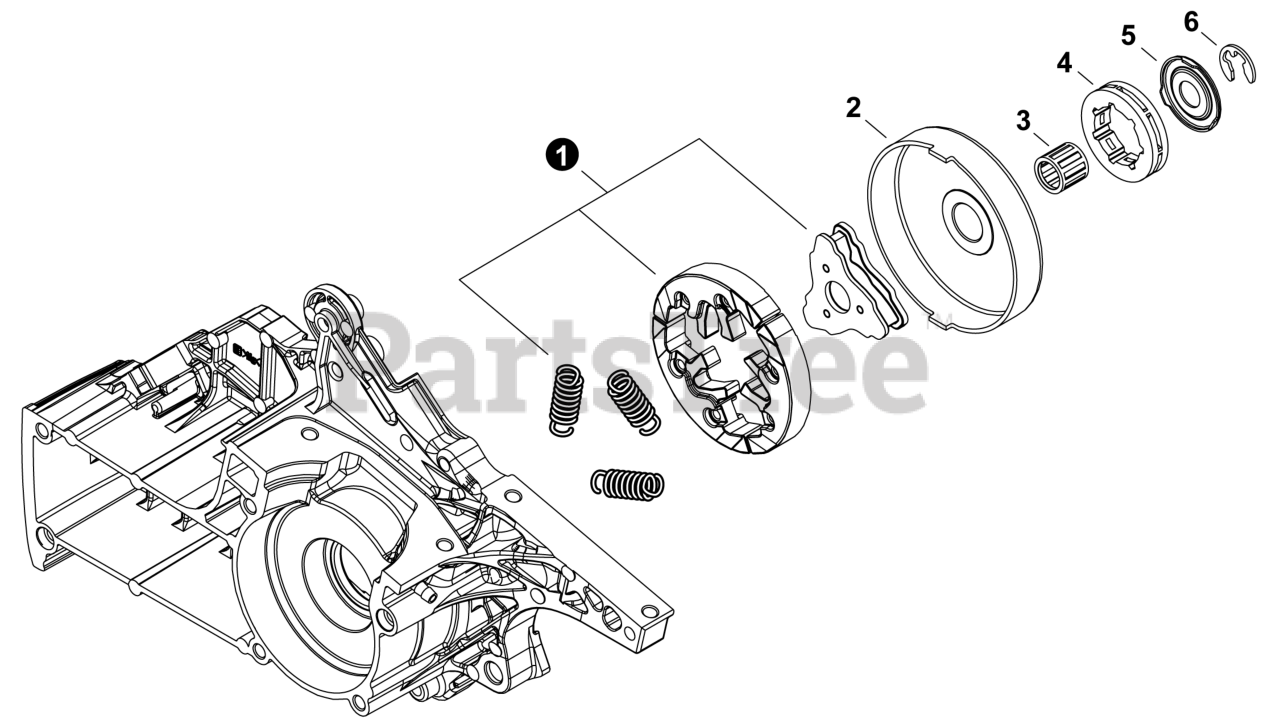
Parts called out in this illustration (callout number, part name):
1	CLUTCH ASSY
2	DRUM, CLUTCH
3	BEARING, NEEDLE 10
4	SPROCKET, RIM 3/8"x7T
5	WASHER 10
6	E-RING 8.1
